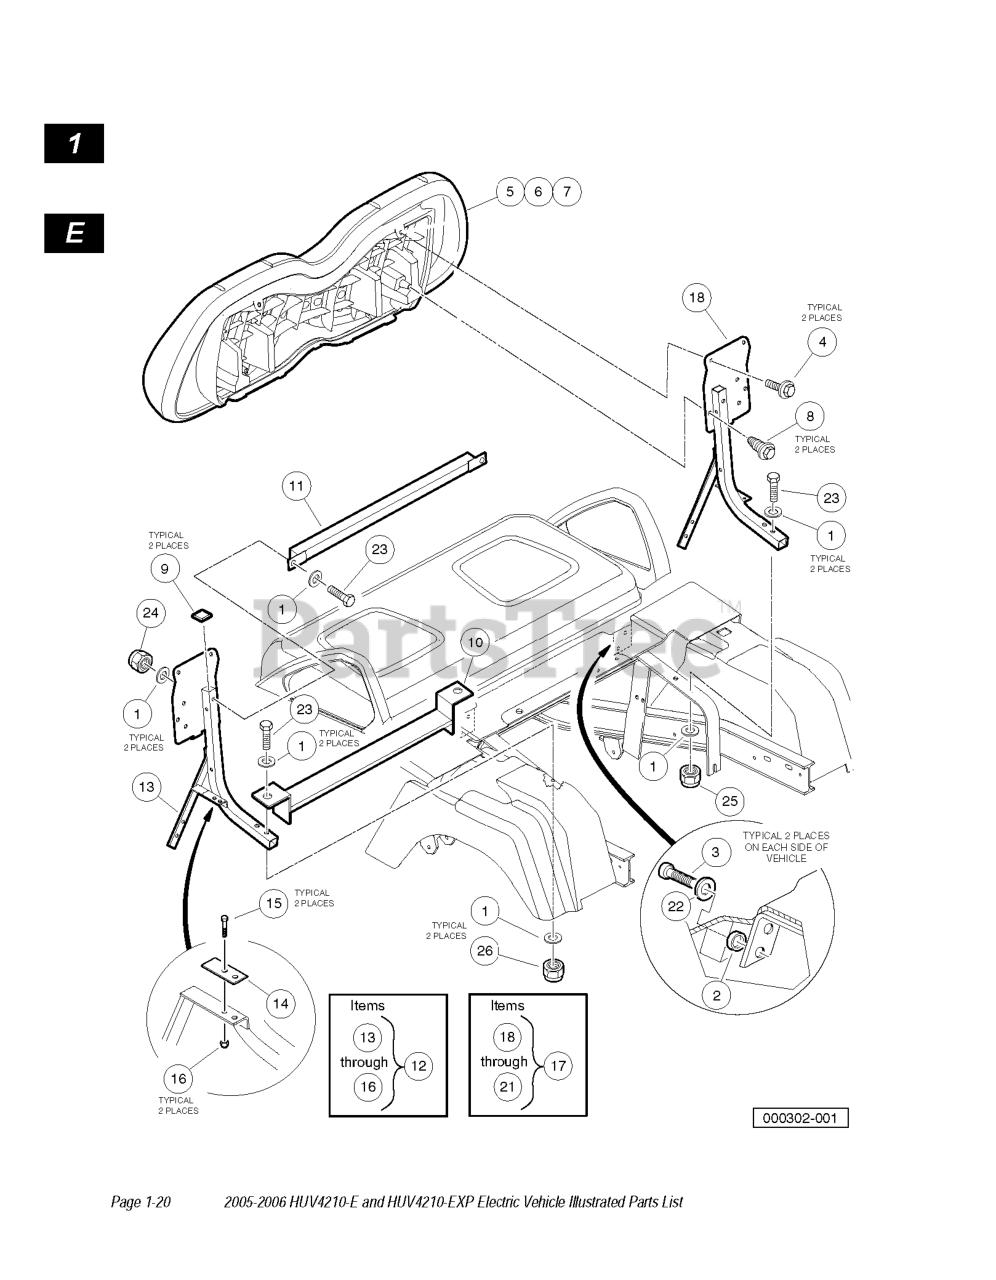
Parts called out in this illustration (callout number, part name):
1	WASHER, 1/4 FLAT
2	BODY SPACER
3	SCREW, 5/16-18 X 1.25 THRD FRM
4	SCREW - M6 X 1.0 X 30 SEMS
7	SERVICE BACKREST ASM-GRAY
8	SCREW, M6 HEX W "CA" POINT
9	PLUG, SQUARE - 25.4 MM
10	WELDMENT-BED SUPPORT
11	SEAT SUPPORT, X BRACE
12	SEAT SUPPORT W/STRIKER,DRIVER
14	STRIKER PLATE
15	SCREW, 1/4-20 X .75 HEX
16	LOCKNUT, 1/4-20 NYLON INSERT
17	SEAT SUPPORT W/STRIKER, PASSEN
19	STRIKER PLATE
20	SCREW, 1/4-20 X .75 HEX
21	LOCKNUT, 1/4-20 NYLON INSERT
22	WASHER, 5/16 TYPE A FLAT
23	SCREW, 1/4-20 X 2.00 HX HD CAP
24	LOCKNUT, 5/16-18 NYLON INSERT
25	LOCKNUT, 1/4-20 NYLON INSERT
26	SCREW, 5/16-18 X 1.75 HX HD CP
